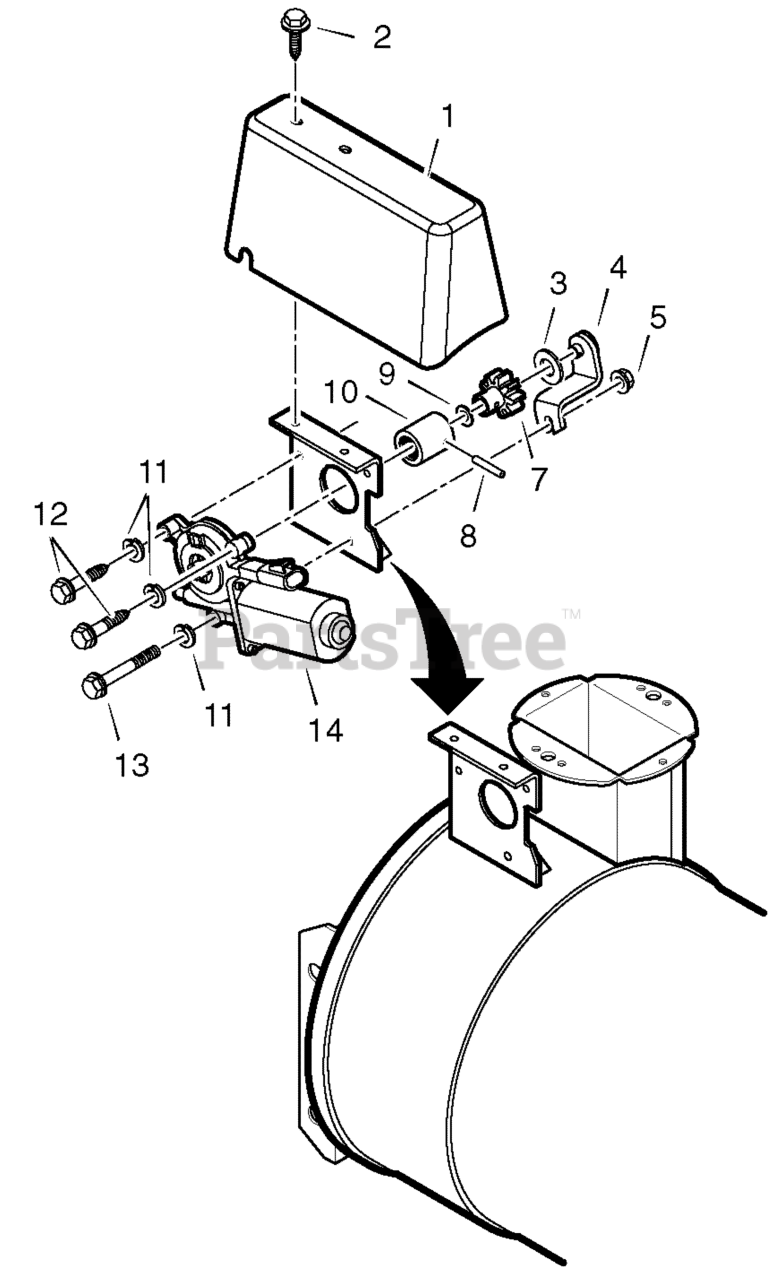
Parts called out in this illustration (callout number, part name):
1	COVER, MOTOR
2	SCREW
3	WASHER
4	BRACE, CHUTE GEAR
5	NUT
7	GEAR
8	PIN, SPRING
9	RING, RETAINER
10	ADAPTER
11	WASHER, SPLIT
13	BOLT, HEX
14	MOTOR, ELECTRIC
